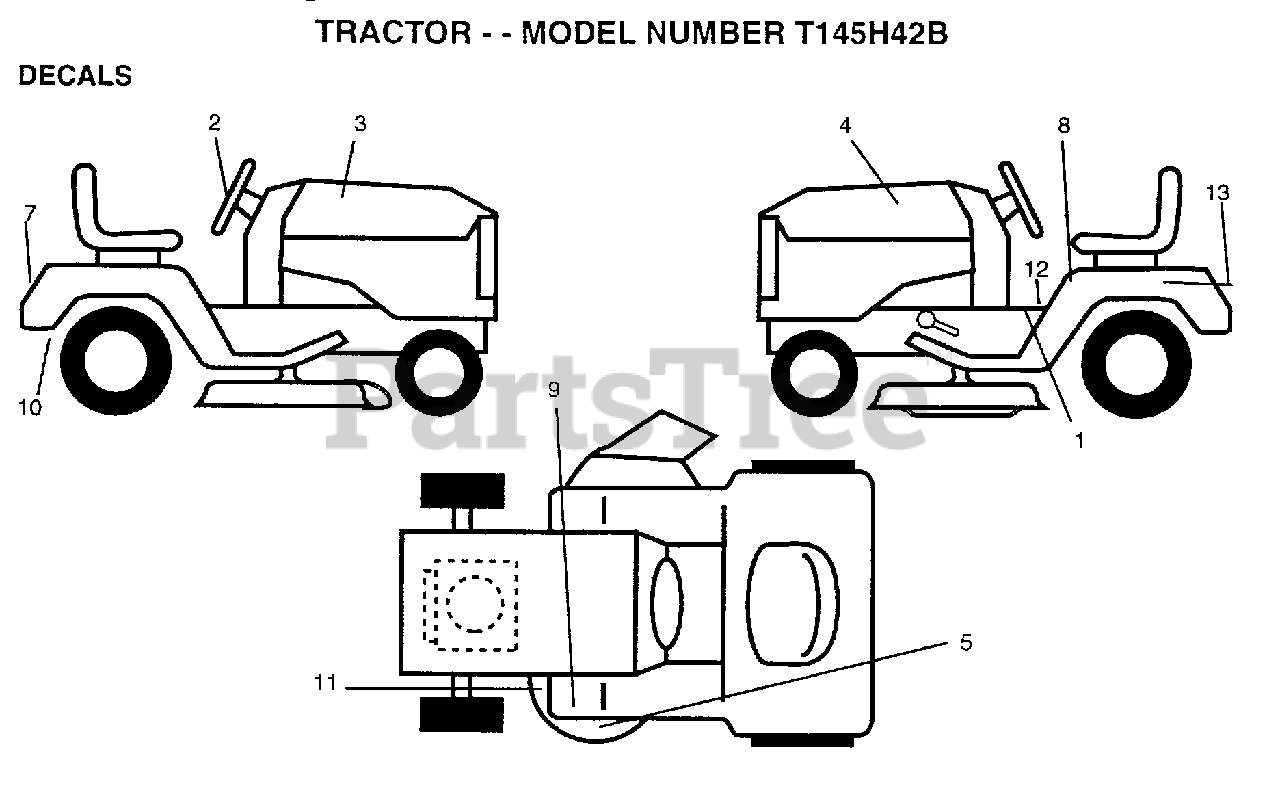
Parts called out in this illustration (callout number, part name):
2	"DECAL,STR WHL T"
3	DECAL.HOOD.RH.CO.
4	DECAL.HOOD.LH.CO.
7	DECAL.FEND.HYD.CP
8	DECAL
10	DECAL DRAWBAR LH
11	DECAL
12	DECAL SADLE HYDRO
13	DECAL.BTRY.DANGER
